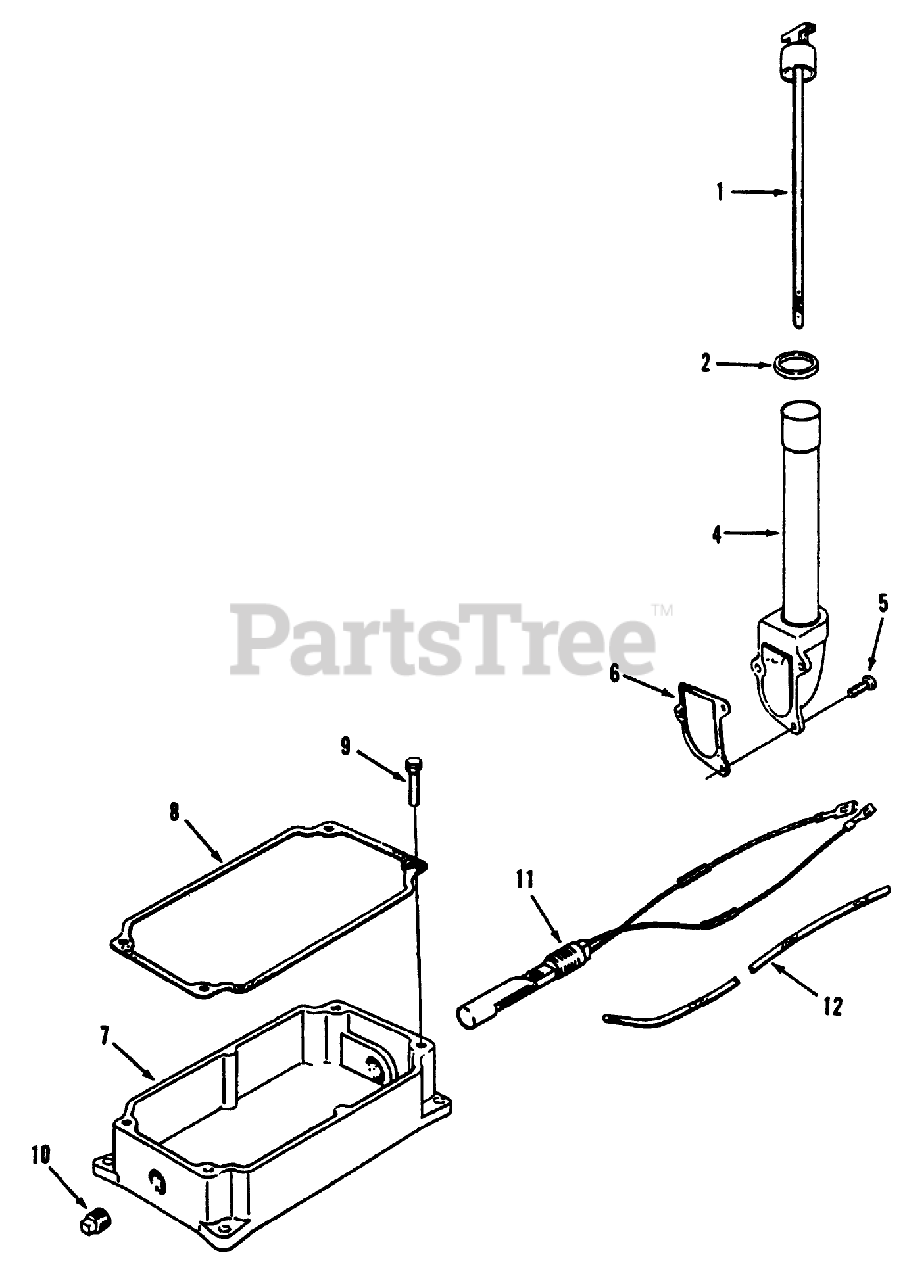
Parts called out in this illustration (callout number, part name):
1	KOHLER 47-038-27
2	KOHLER 41-153-01
4	KOHLER 47-029-06
5	KOHLER X-131-2
6	KOHLER 237064
7	KOHLER 45-199-05
8	KOHLER 235057
9	KOHLER X-159-3
10	KOHLER X-75-10
11	KOHLER 47-099-04
12	KOHLER 25-431-02
